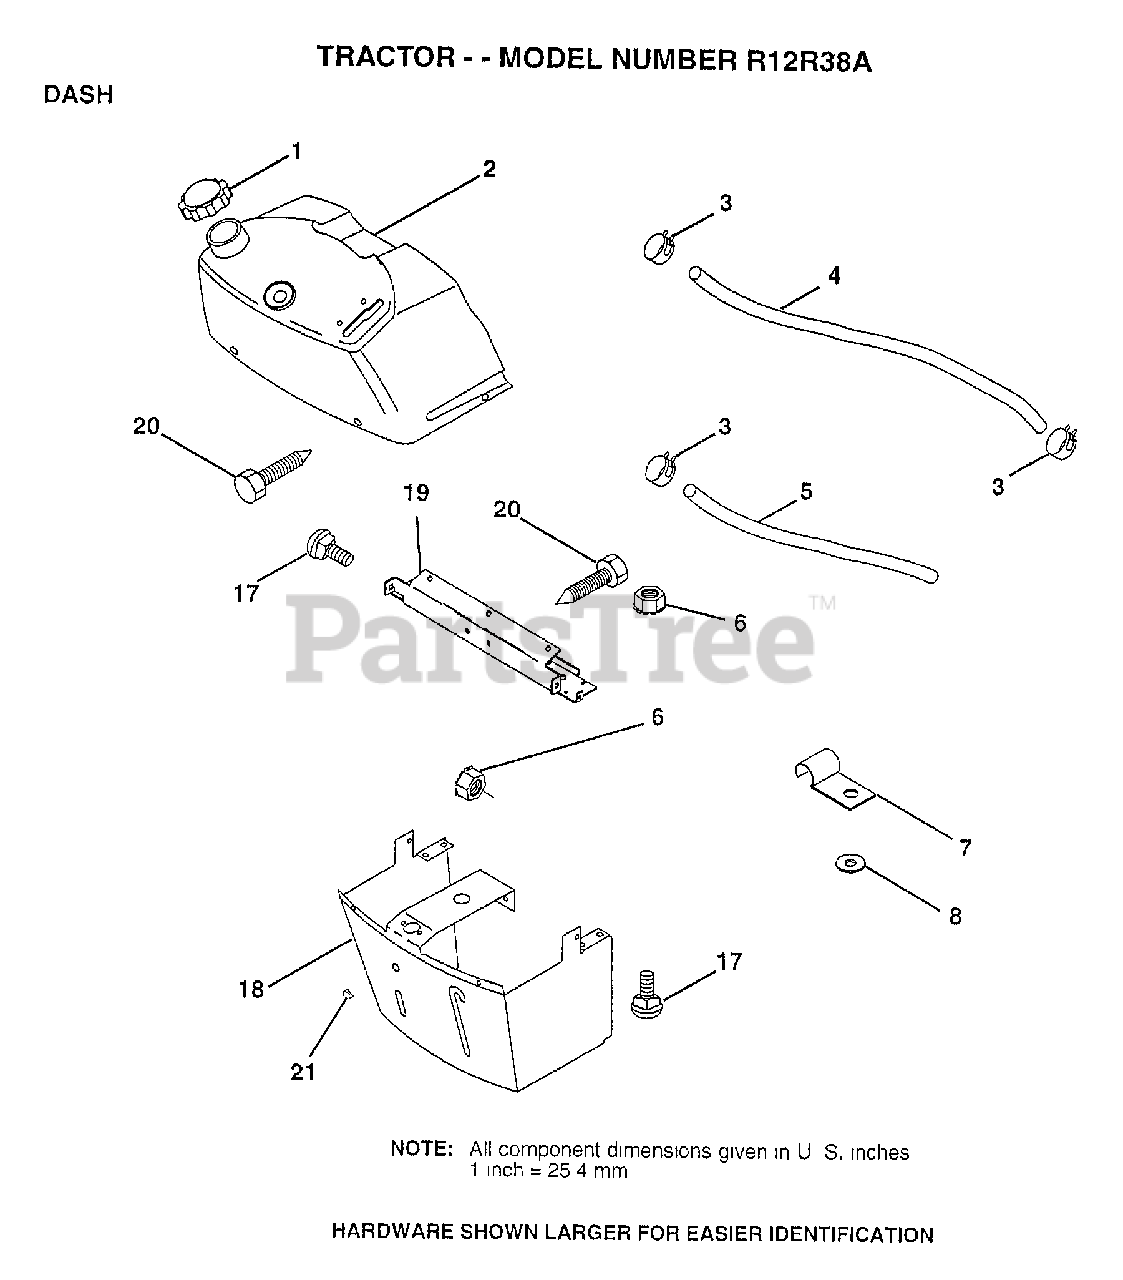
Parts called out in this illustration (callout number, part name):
1	CAP BLK FUEL LR
2	TANK.ASM.DASH.LR
3	HOSE CLAMP
5	FUEL LINE T
6	NUT HXKEP 1/4X20
7	CLIP T
8	CONFLICT W/PART #
17	BOLT
18	SUPT ASM DASH
19	CROSS BRACE
20	SCREW.1/4-20X1/2
21	PLUG DOME
